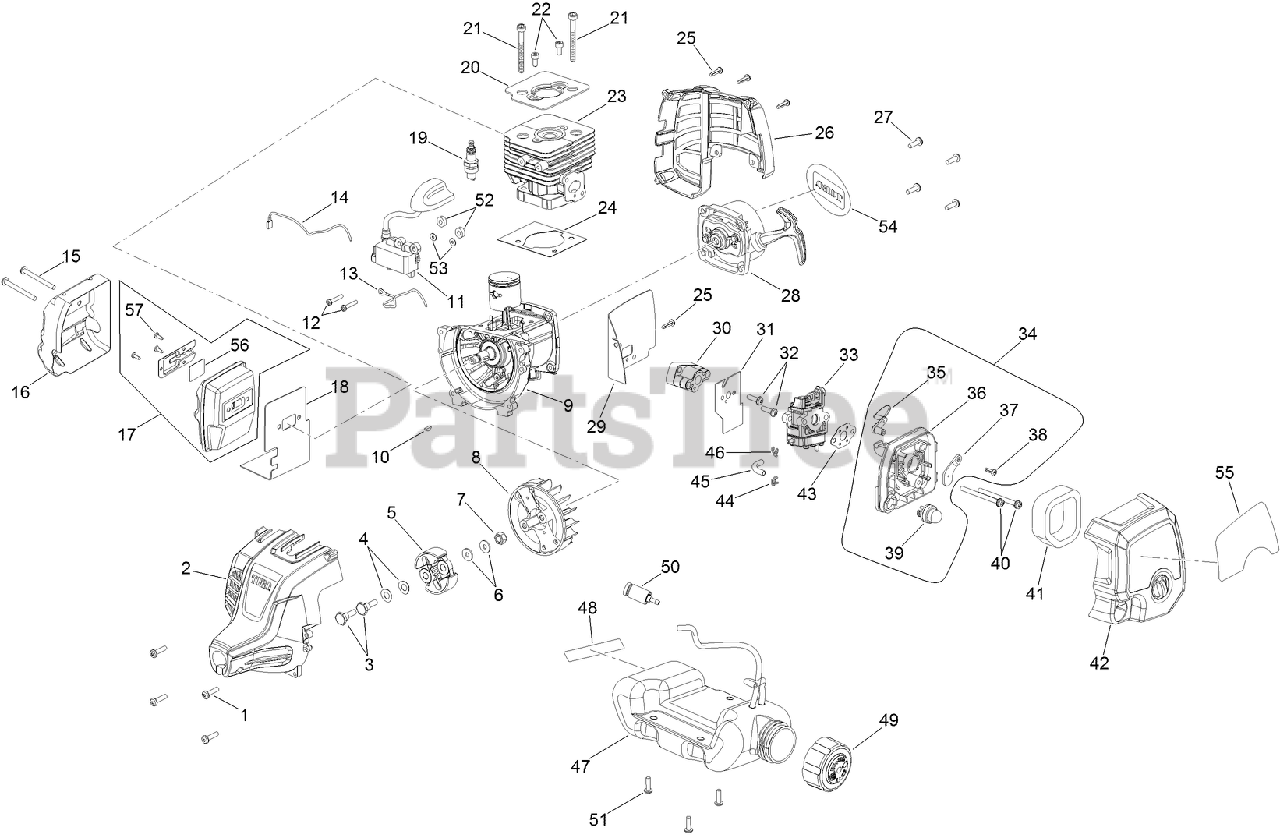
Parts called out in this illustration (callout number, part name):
1	SCREW-PH
2	HOUSING-ENGINE, FRONT
3	SCREW-CLUTCH
4	WASHER-CURVED
7	NUT-ROTOR
9	CRANKCASE ASM
10	KEY-WOODRUFF
11	COIL BOOT ASM
12	SCREW-PH
13	WIRE-LEAD, RED
14	WIRE-LEAD, BLACK
15	SCREW-PH
16	SHIELD-HEAT
17	MUFFLER ASM
18	GASKET-MUFFLER
19	SPARK PLUG
20	PLATE-CYLINDER
21	SCREW-SOCKET HEAD
22	SCREW-PH, TORX
23	CYLINDER
26	HOUSING-ENGINE, REAR
27	SCREW-PH
28	RECOIL STARTER AND STARTER CUP ASM
30	INSULATOR-DAM, HEAT
32	SCREW-PH
33	CARBURETOR ASM
34	FILTER HOUSING ASM
35	LEVER-CHOKE
36	PLATE-CARBURETOR
37	PLATE-CHOKE
38	SCREW-PH
39	PRIMER ASM
40	SCREW-PH
41	ELEMENT-FILTER, AIR
42	COVER ASM
44	CLIP-HOSE
45	LINE-FUEL
46	CLIP-HOSE
47	FUEL TANK AND CAP ASM
48	LABEL-COMBUSTION
49	CAP-FUEL
50	FILTER-FUEL
54	PLATE-LOGO
55	DECAL-START
57	SCREW-PH
